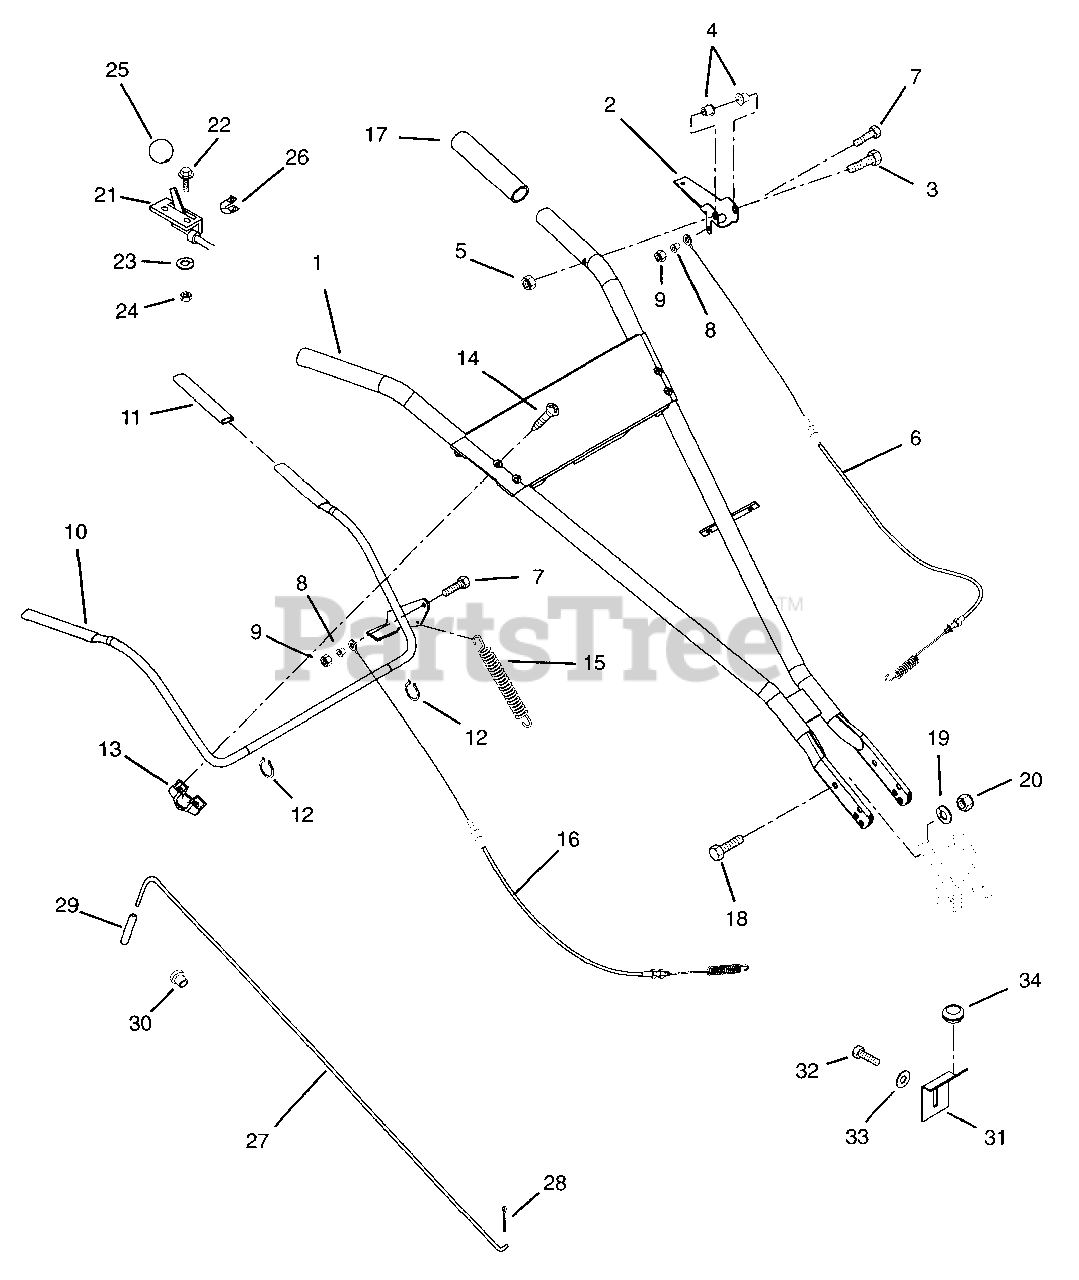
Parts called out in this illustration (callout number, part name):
1	HANDLEBAR- 8 HP TILLER
2	HANDLE, REVERSE
3	@BLT-HEX .31-18X2.25 GR5 YWZC
4	BSHG-FLG .325X.465X.333X.685
5	@NUT-LK-CTR .31-18 YWZC
6	CABLE, REV 8HP
7	@BLT-HEX .25-20X1.00 GR5 YWZC
8	BSHG-FLG .253X.373X.385X.500
9	@NUT-LK-CTR .25-20 YWZC
10	BAIL, FWD
11	GRIP, TILLER - OPC
12	RG-RTNG-EXT .500X.042 (E)
13	PIVOT, BAIL
14	SCR-TAP 12-24X1.50 CROVH YZ BT
15	SG-TENS .051X.50X5.12 WLD 10.4
16	CABLE, FWD
17	HANDLEGRIP
18	@BLT-HEX .38-16X1.00 GR5 YWZC
19	@WSHR-LK .38X.094 REG YWZC
20	@NUT-LK-CTR .38-16 YWZC
21	THROTTLE CONTROL B&S RT8020
22	SCR-MCH 10-24X.50 SLRH BL
23	@WSHR-LK #10X.047 REG YWZC
24	@NUT-HEX 10-24 YWZC
25	KNOB, CONTROL-THROTTLE
26	OUTPUT GEAR
27	ROD, POSITION
28	@PIN-CTR .12X.75 EXTPRSQCT YWZ
29	GRIP - 5/16 ID X 2 7/8 - BLACK
30	SNAP BUSHING
31	PIVOT FEED
32	@BLT-HEX .25-20X.75 GR5 YWZC
33	@WSHR-FL-STL.281X.62X.065 YWZC
34	GRMT .75X1.06X1.38
